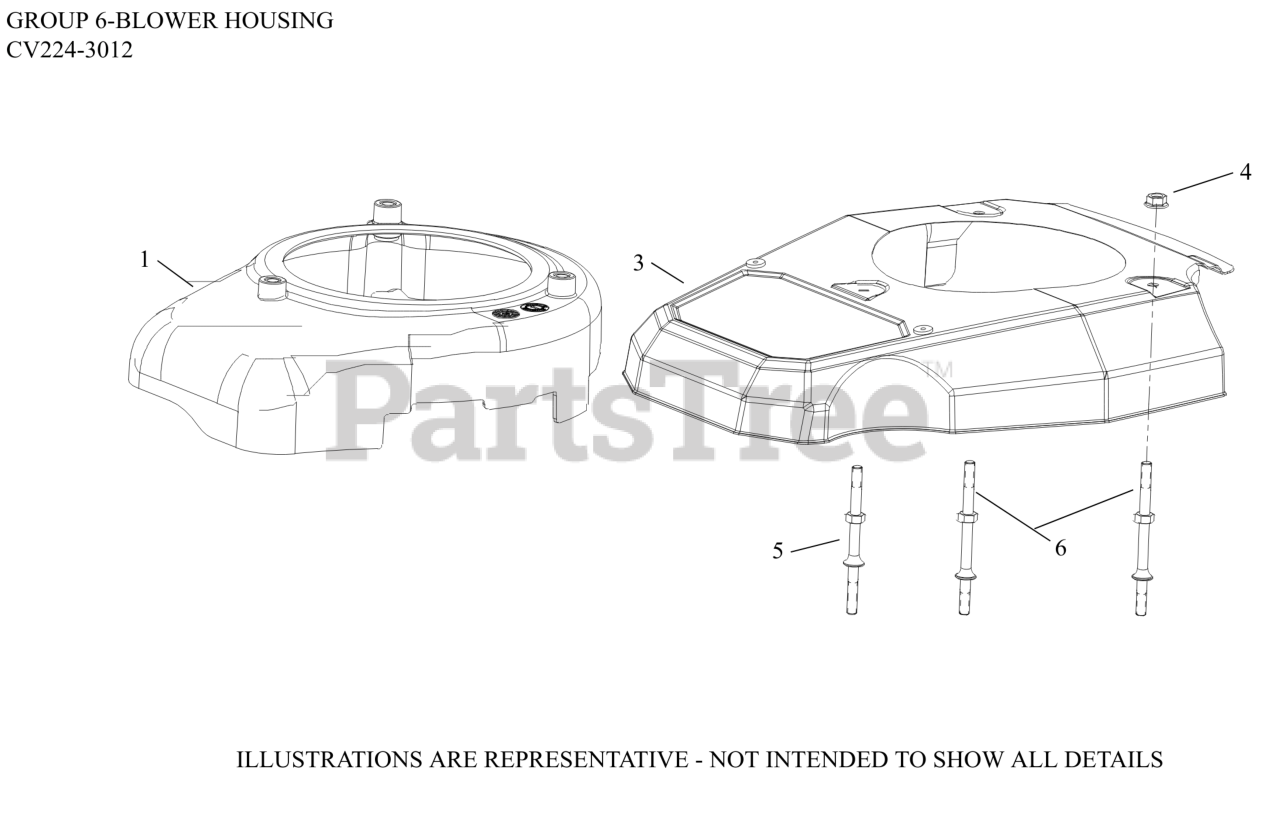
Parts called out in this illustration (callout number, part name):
1	KIT, BLOWER HOUSING
3	COVER, ENGINE
4	NUT, HEX FLANGE (M6) - USE 14 100 16-S
5	STUD-USE 14 072 25-S
6	STUD, BLOWER HOUSING
